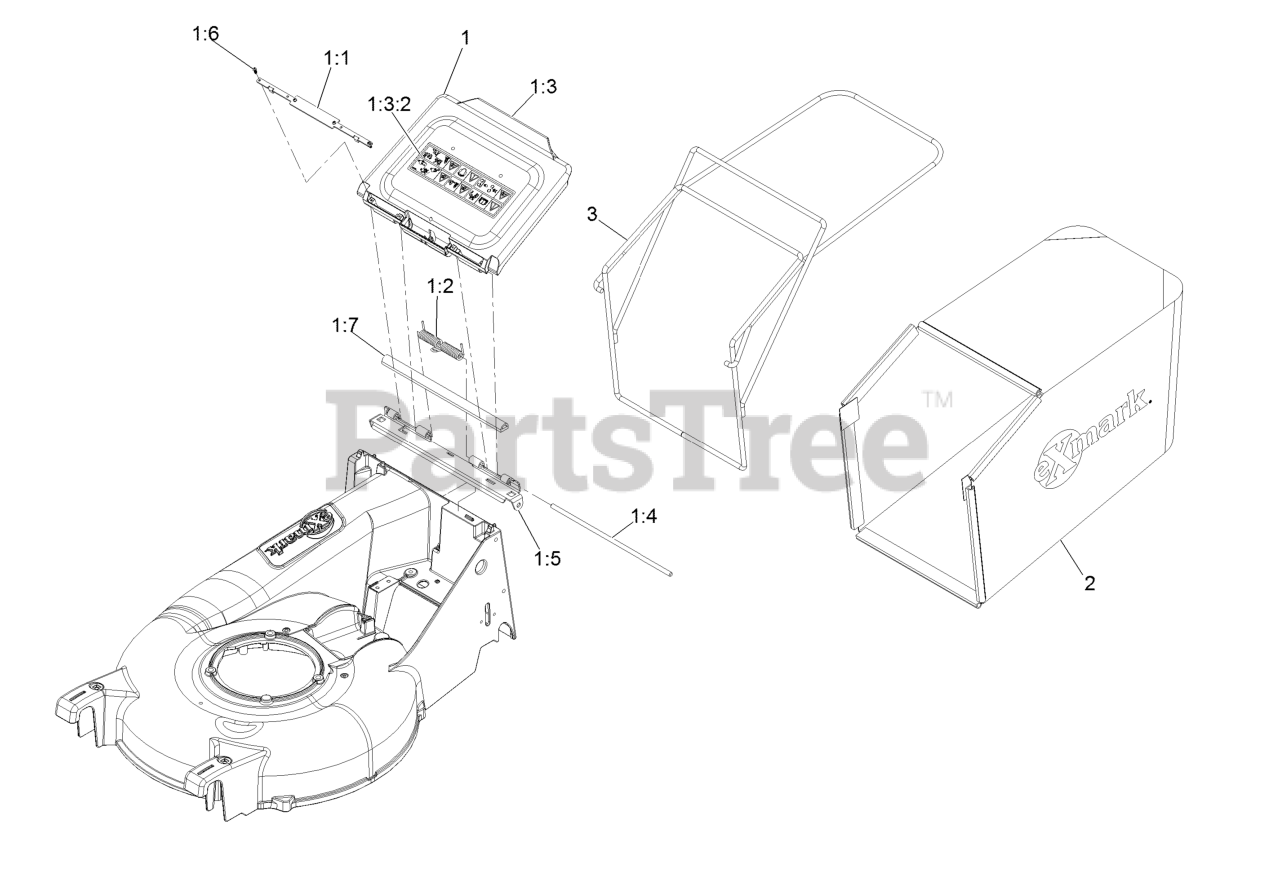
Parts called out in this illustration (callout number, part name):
1	Door ASM
1:1	Plate, Door Cover
1:2	Spring-Plastic Door
1:3	ASM-Door & Decal
1:3:2	Decal-Warning
1:4	Pin-Door Pivot
1:5	Bracket-Door Pivot
1:6	Screw-PPHTF #6-19 X 7/16
1:7	Seal-Epdm Foam Bulb
2	Bag-21 Grass
3	Wld-Bag Frame
